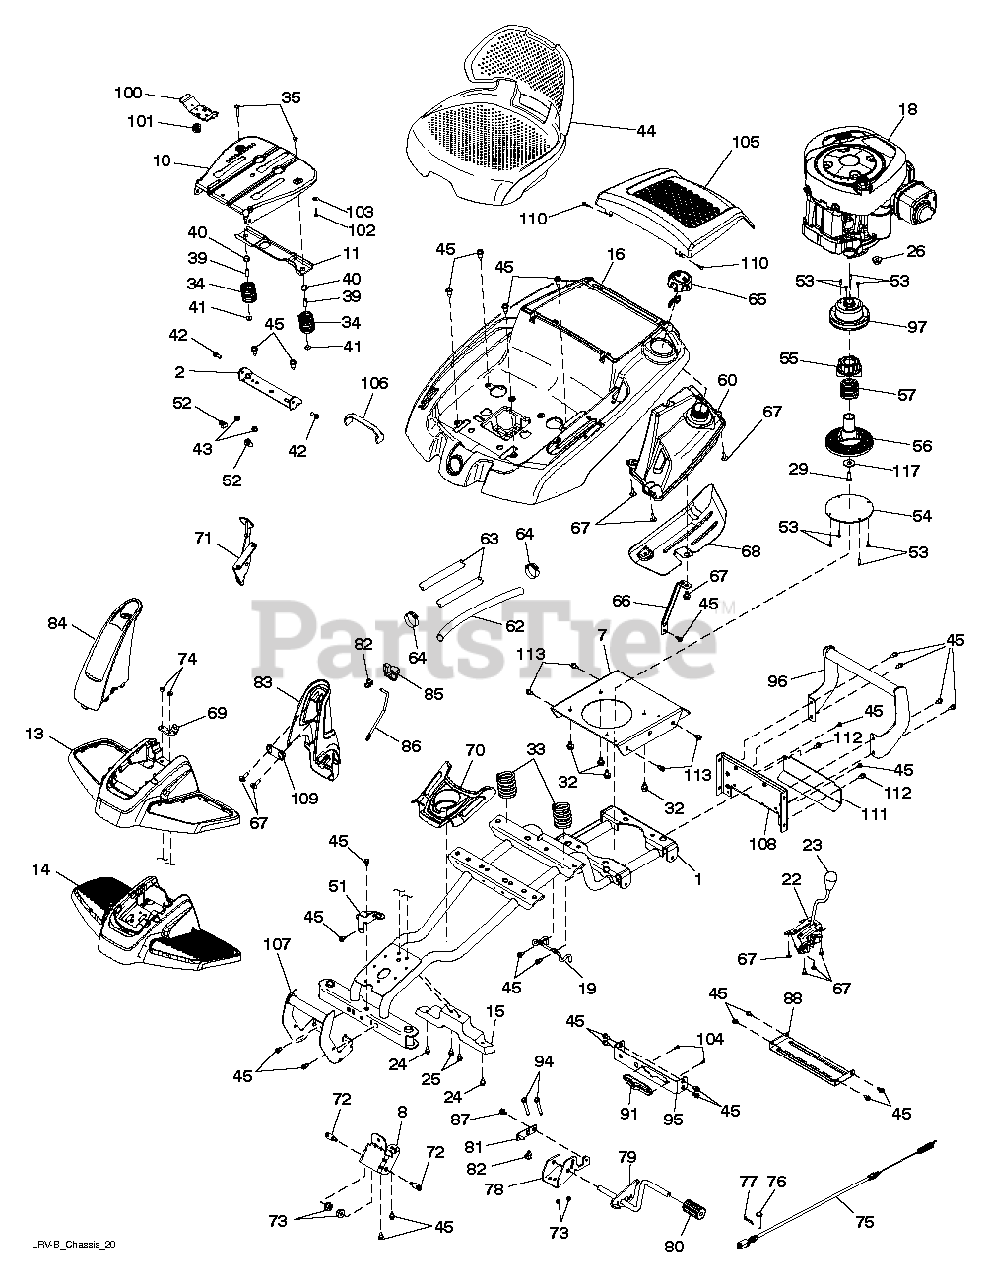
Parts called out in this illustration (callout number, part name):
2	BRKT.PIVOT.FENDER
8	BRACKET.SUSP.CHAS.FR.LRV
10	PAN.ASM.SEAT.SHORT.SLD.ADJ.TEX
11	BRKT.MNT.OPC.SW.SEAT.
13	COVER.AESTH.FOOTREST.MS428
14	FOOTREST.STRUCTURAL.
15	SUPPORT. FOOTREST.LRV.MS428
23	KNOB.OVAL.CUSTOM.BLACK
24	SCREW.#10 X 0.750.BOS (2 2)
25	BOLT.CARRIAGE
26	NUT
32	SCREW.3/8-16
33	SPRING COMPRESSION
34	SPRING COMPRESSED
35	BOLT.ROUND.HEAD.SQUARE.NECK
39	SPACER SPLIT 28X.96
41	NUT T
42	BOLT.SHOULDER.5/16-18
43	NUT.71038.31-18.HEX.NYLOCK
44	COMFORT.SEAT.ASSEMBLY
45	SCREW
51	BRACKET, STEERING SUPPORT
52	PUSH CLIP
53	SCREW.#10X.750 *SUBS/2*
54	DISC.FRICTION.LRVB
55	TORSION.BODY.UPPER
56	TORQUE ASM.CONTROL.LOWER
57	SPRING.HELIX
60	LRVB.FUEL.TANK.ASSEMBLY.EPA
63	RP PURGE LINE
64	HOSE CLAMP
65	CAP.2.25'.VENTED.RATCHET.EPA
67	SCREW.#10 X 0.500
70	CONSOLE.CENTER.CUPHOLDER
72	STUD.FASTNER.W/ANTI-ROTATE
73	NUT LOCK HEX FLANGE 5/16-18
74	NUT T
75	CABLE,BRAKE.LRVB
76	PIN.CLEVIS
77	COTTER PIN
80	COVER.PEDAL.BRAKE.LRV
82	RETAINER CLIP
87	BOLT.SHOULDER.5/16-18X
88	STRAP.CROSS.FRICTION.DRIVE
94	BOLT HEX FLGHD 5/16-18X3 GR. 5
96	BUMPER.REAR.WELDMENT.BLACK.LRV
100	HANDLE.SLIDE.SEAT.TEX.BLACK
101	SPRING.LATCH.SEAT.TEX
103	WASHER 13/32 X 2-3/8 X 12GA
104	SCREW.TORX.#10-14X1/2
105	Engine Cover, Lrvb Pattern 2.X428
106	STRAP.BATTERY.LRVB
107	WELDMENT.FRT.PNT.BRUSHGAD.LR
112	SCREW
113	SCREW 5/16"
117	WASHER.1.5X.505X.118
